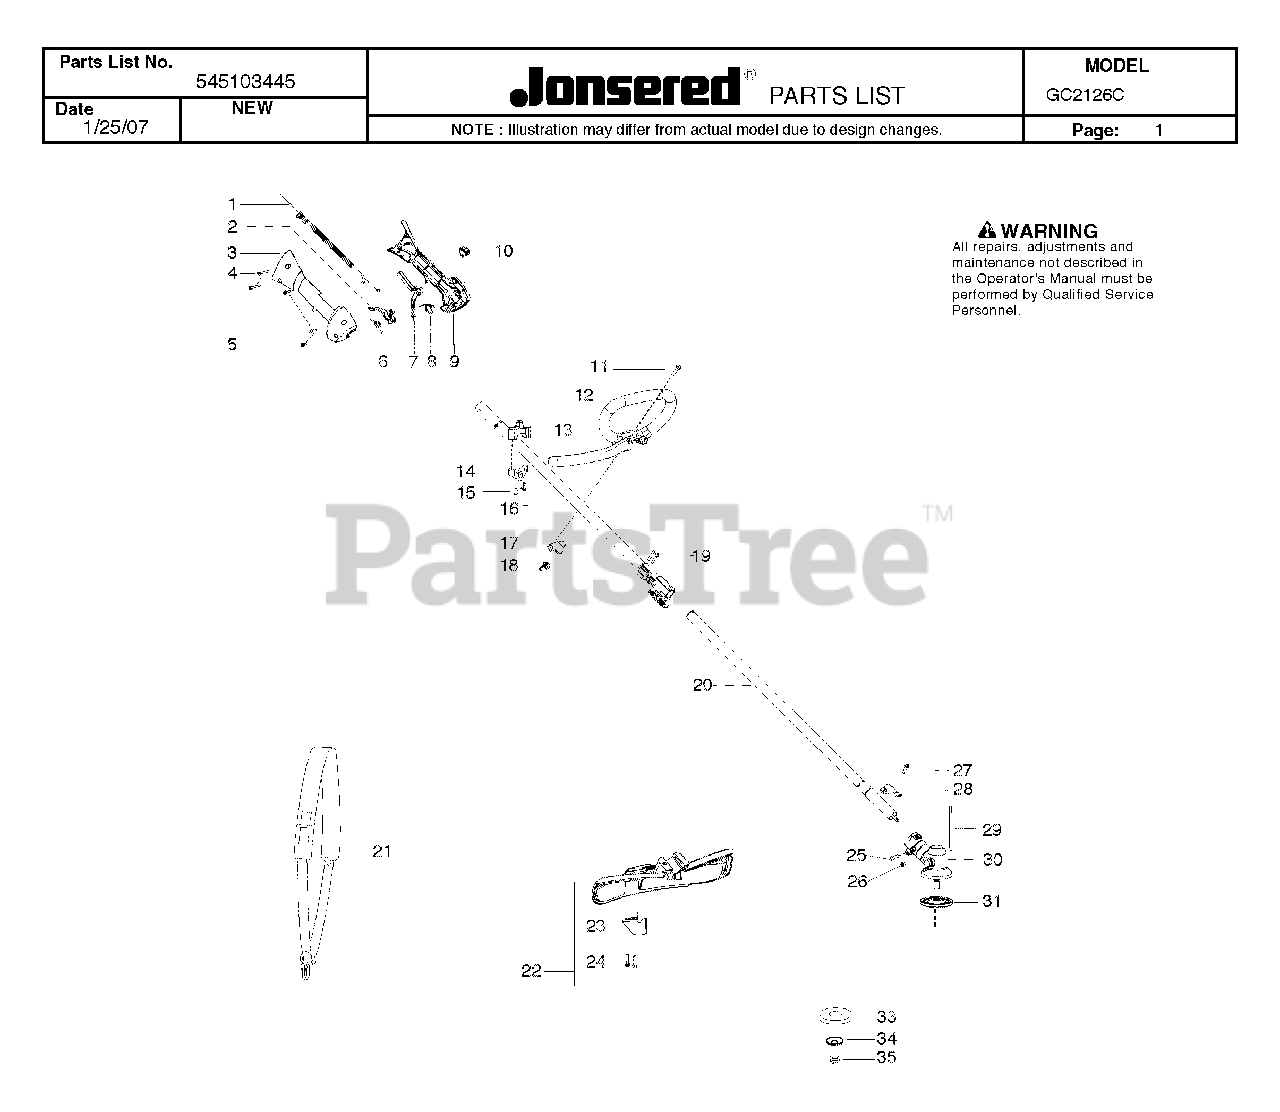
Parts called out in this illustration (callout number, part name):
1	%ASSY CABLE WIRE HARNESS
5	SCREW M4 X 1.75 PT 16MM
6	SPRING TRIGGER
8	SPRING LOCKOUT
10	KIT SWITCH
11	BOLT, TYPE 2
13	CLAMP HARNESS UPPER
14	CLAMP HARNESS LOWER
17	CLAMP ASSIST HANDLE
18	WINGNUT, TYPE 2
21	STRAP
21	SHOULDER STRAP WITH SIGN
22	KIT SHIELD
23	LINE CUTTER
25	SCREW - CARB. ADAPTOR
27	SCREW 1/4-20 X 7/8 (TAP
28	BRACKET SHIELD STRAIGHT SHAFT
29	LOCKING PIN
30	ASSY GEARBOX
31	DRIVE DISC
33	SUPPORTING CUP
34	SUPPORT FLANGE
35	GEARHEAD NUT - BRUSHCUTTER
